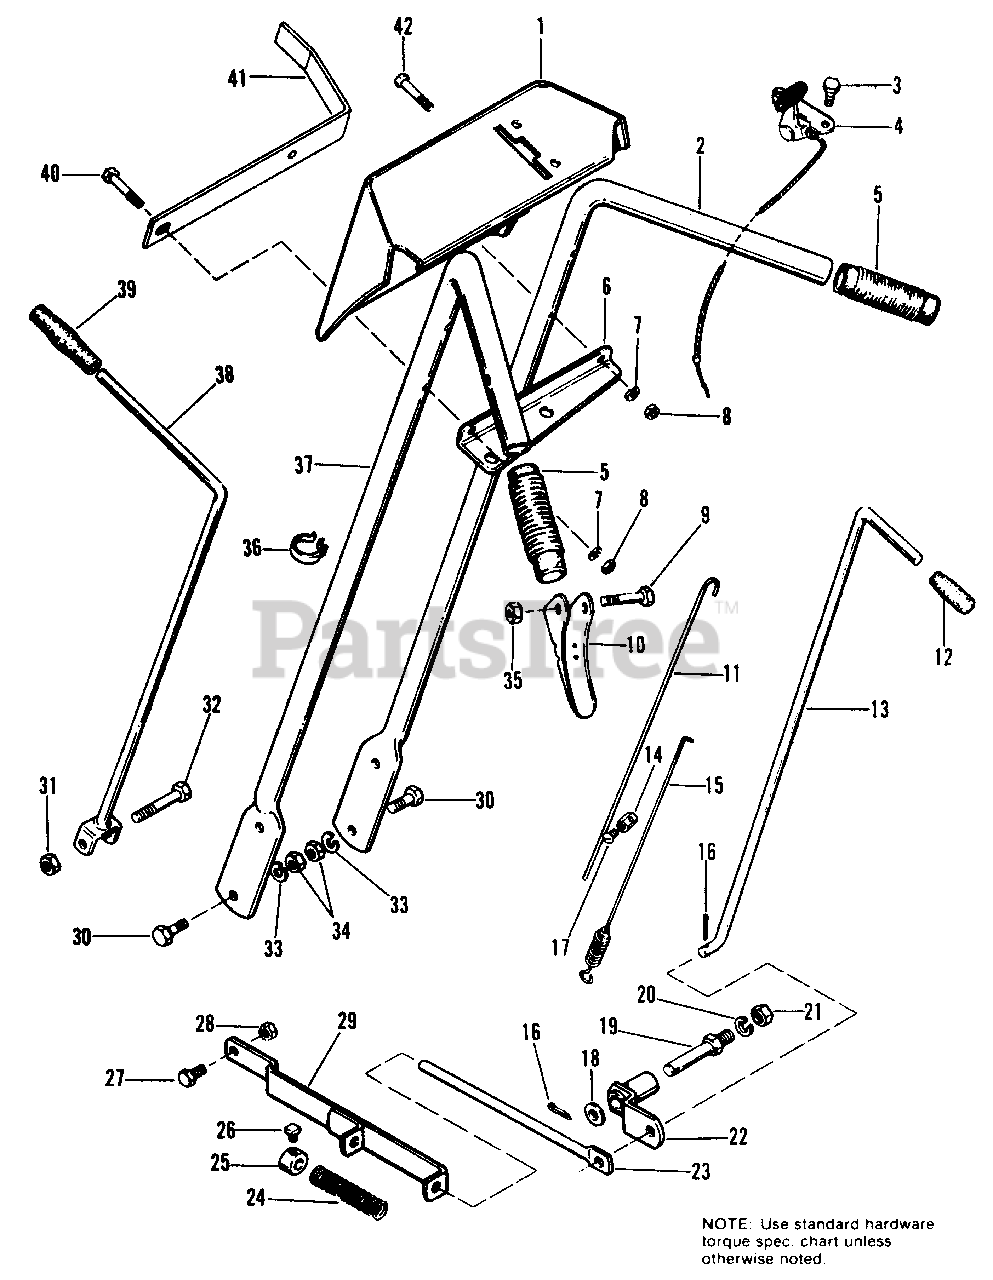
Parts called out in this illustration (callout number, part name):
1	CONTROL HOUSING ASSY.
2	HANDLE, R.H. (990643, 990652, 990656 & 990742 Only)
2	HANDLE, R.H. (990796, 990869 & 990870 Only)
3	SCREW, Self Tapping, 1/4-20
4	CONTROL ASSY.
6	GUIDE, Rod
7	LOCKWASHER, 1/4
8	NUT, Hex, Full, 1/4-20
9	CAPSCREW, Hex, 1/4-20 x 1-1/2
10	GRIP, Clutch
11	EXTENSION, Spring
13	ROD, Idler
14	CLAMP, Wire
15	SPRING ASSY. (990643, 990652, 990656 & 990742 Only)
15	SPRING ASSY. (990796, 990869 & 990870 Only)
16	PIN, Cotter, 1/8 x 3/4
17	SCREW, Rd. Hd., #10-24 x 3/8
18	WASHER, Plain, 3/8
20	LOCKWASHER, 7/16
21	NUT, Hex, Full, 7/16-14
22	PIVOT ASSY.
23	ROD, Clutch
25	SET COLLAR
26	SCREW, Sq. Hd., 1/4-20 x 3/8
27	CAPSCREW, Hex, 5/16-18 x 5/8
28	LOCKNUT, Hex, 5/16-18
29	GUIDE ASSY., Rod
30	CAPSCREW, Hex, 5/16-18 x 7/8
31	LOCKNUT, Hex, 5/16-18
32	CAPSCREW, Hex, 5/16-18 x 2
33	LOCKWASHER, 5/16
34	NUT, Full, Hex, 5/16-18
35	LOCKNUT, Hex, 1/4-20
36	CLIP, Cable
37	HANDLE, L.H. (990643, 990652, 990656 & 990742 Only)
37	HANDLE, L.H. (990796, 990869 & 990870 Only)
38	ROD ASSY., Shift, Upper
39	GRIP, Handle
40	CAPSCREW, Hex, 1/4-20 x 1-3/4
41	BRACKET, Support
42	CAPSCREW, Hex, 1/4-20 1-1/2
